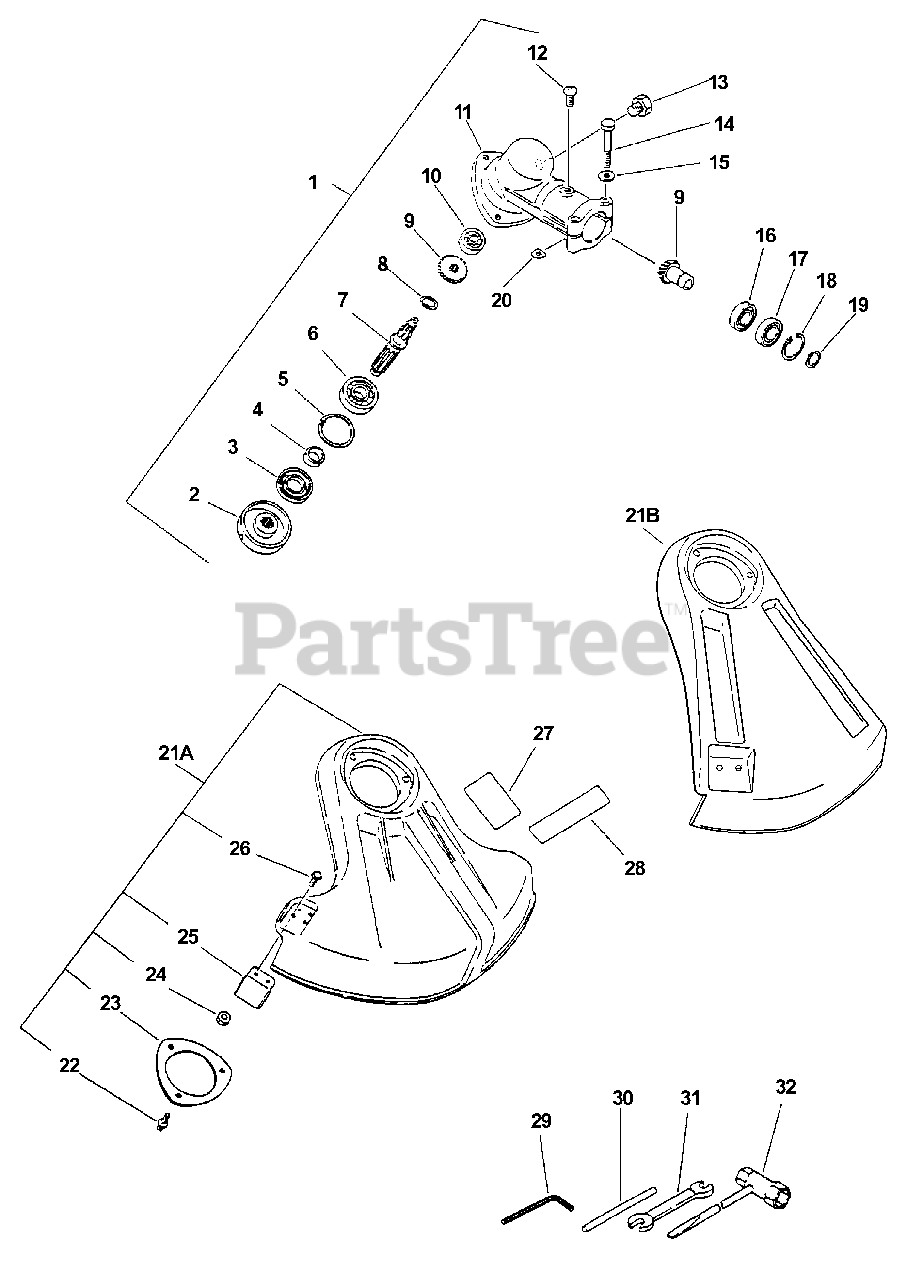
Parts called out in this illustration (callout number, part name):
1	GEAR CASE ASSY
2	ADAPTOR, BLADE - UPPER
3	SEAL, OIL
5	RING, RETAINING - 32
6	BEARING, BALL - 6201
7	GEAR - SHAFT
8	RING, RETAINING - 10
9	GEAR SET - BEVEL
10	BEARING, BALL - 609
11	CASE, GEAR
12	SCREW - 5X10
13	BOLT - 8X8
14	BOLT - 5X35
15	WASHER - 5
16	BEARING, BALL - 6900
17	BEARING, BALL - 6900Z
18	RING, RETAINING - 22
19	RING, RETAINING - 10
21A	DEBRIS SHIELD KIT
21B	DEBRIS SHIELD KIT
22	SCREW - 5X16
23	PLATE, SHIELD
25	KNIFE, TRIMMER LINE
26	SCREW - 5X16
27	LABEL - CAUTION
28	LABEL - ECHO
29	HEX KEY - 4mm
30	LOCKING TOOL
31	SPANNER - 8X10mm
32	T-WRENCH - 17X19mm
